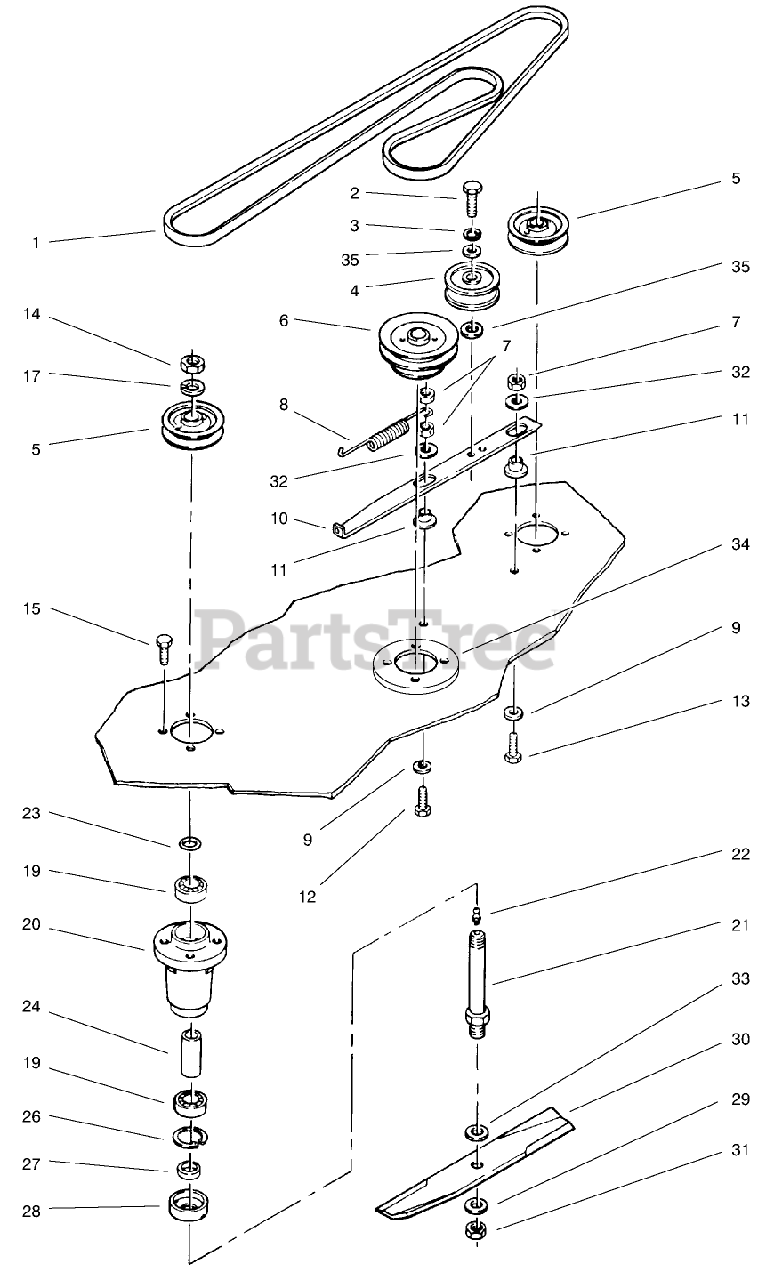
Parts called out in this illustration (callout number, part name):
1	V BELT
2	SCREW-HH
3	WASHER-LOCK
4	PULLEY-IDLER, FLAT
5	PULLEY
6	PULLEY
7	NUT-LOCK, NI
8	SPRING-EXTENSION
9	WASHER
10	BAR-IDLER SUPPORT
11	SPACER-BUSHING
12	SCREW-HH
13	SCREW-HH
14	NUT-JAM
15	SCREW-HH
16	Spindle Assembly (Incl. Ref.# 19-28)
17	WASHER-LOCK
19	BEARING-BALL
20	HOUSING-SPINDLE
21	SHAFT-SPINDLE
22	FITTING-GREASE
23	O RING
26	RING-RETAINING
27	SPACER-BLADE
28	CUP-SPINDLE
29	WASHER-FLAT
30	14IN BLADE KIT
31	NUT-JAM
32	WASHER
33	WASHER-FLAT
34	PLATE-SPINDLE
35	WASHER-FLAT
